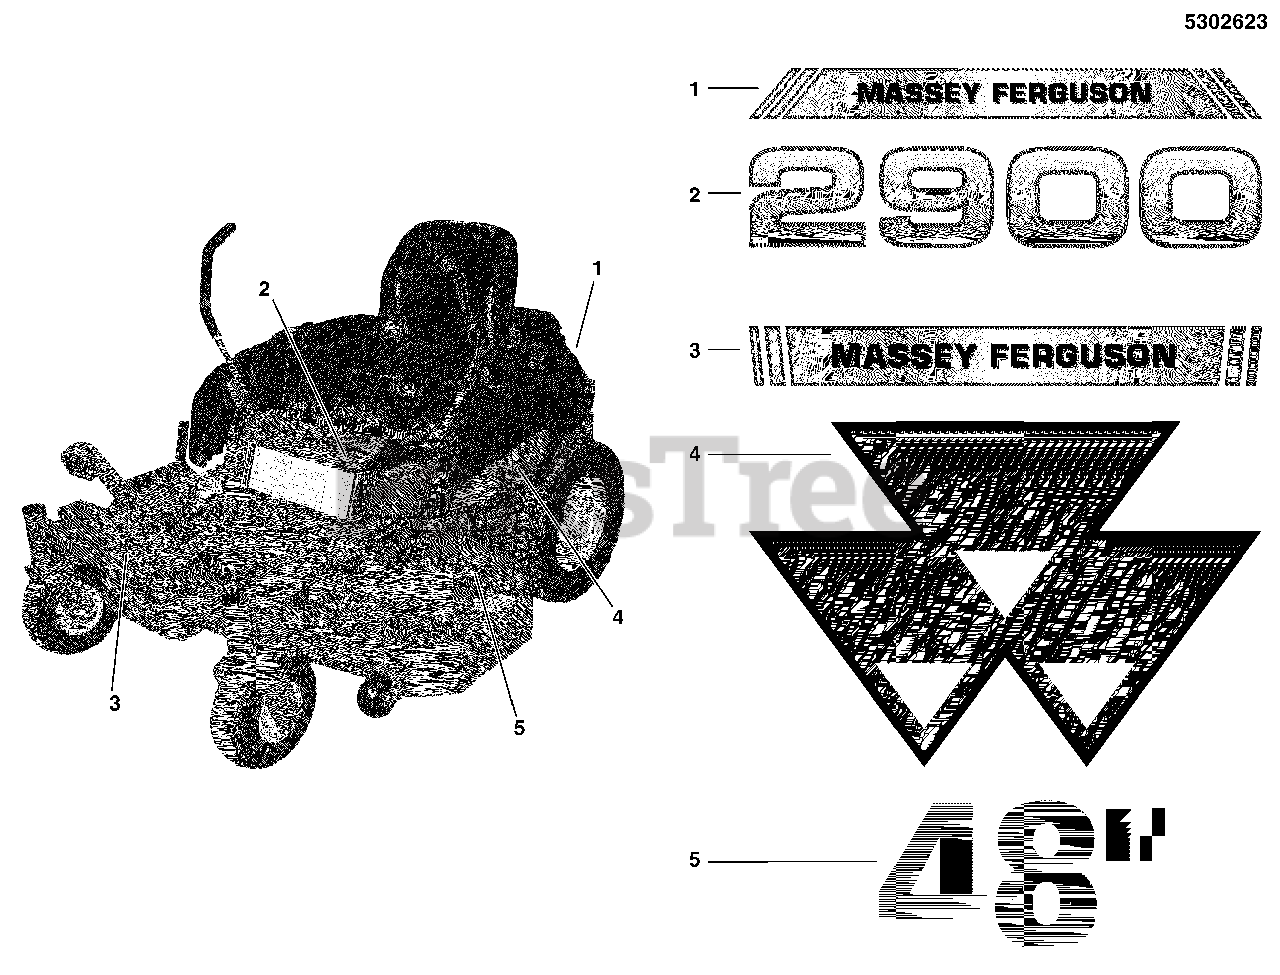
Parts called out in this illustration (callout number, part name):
1	DECAL, MASSEY LOGO BACK
2	DECAL, MF MODEL, 2900
3	DECAL, MASSEY, FRONT, 2900
4	DECAL, MASSEY LOGO SIDE PANEL
